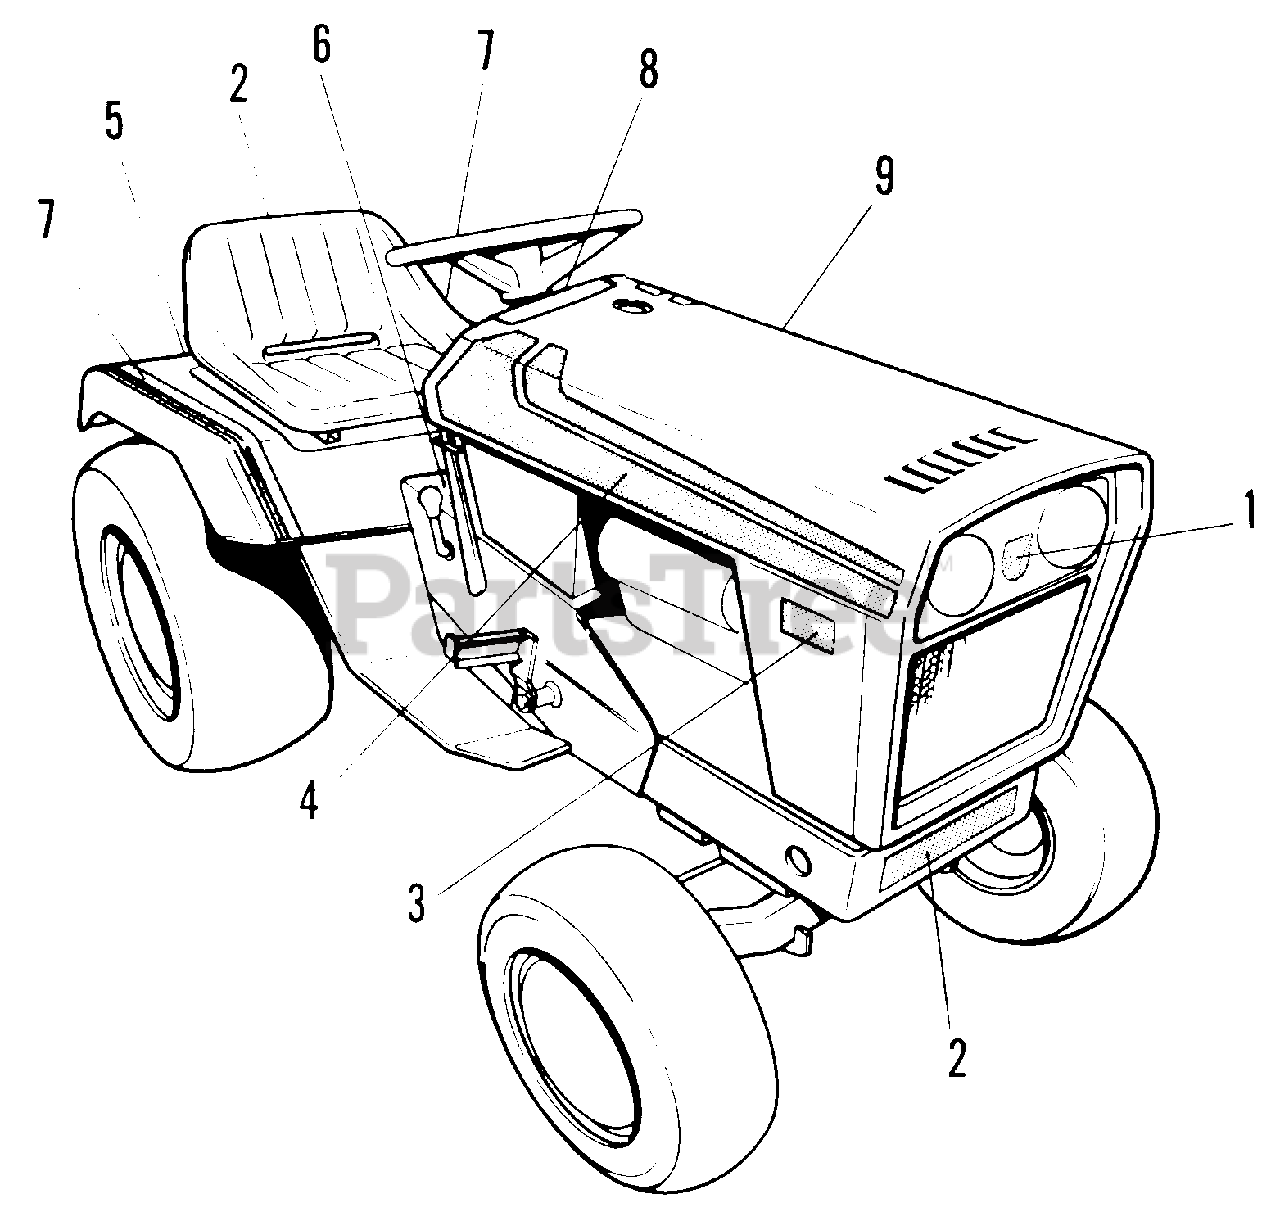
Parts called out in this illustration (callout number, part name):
1	DECAL, Simplicity Grille
2	DECAL, Simplicity
3	DECAL, Model 7116 Hydro
3	DECAL, Model 7117 Hydro
4	DECAL, Hood Stripe, RH
5	DECAL, Cast Iron Trans.
6	DECAL, Console, Hydro
7	DECAL, Seat Deck
8	DECAL, Dash, Hydro
9	DECAL, Hood Stripe, LH
